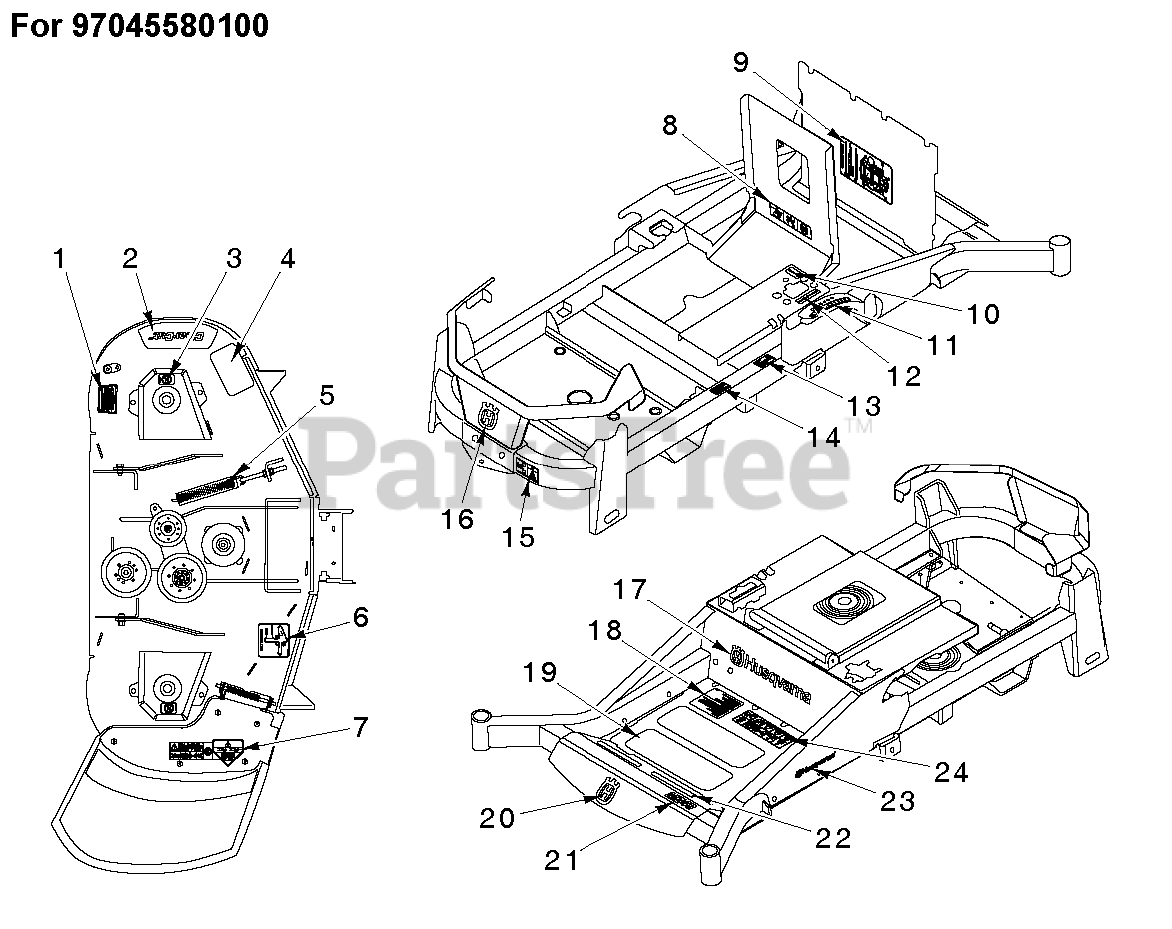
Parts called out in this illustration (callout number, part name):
1	DECAL DECK DECAL DECAL.DECK.WA
2	DECAL DECK DECAL DECAL.48DECK.
3	DECAL.DECK.CLEARCUT.NOSTEP
5	VIBRATION PAD
6	DECAL, BELT ROUTING
7	DECAL.TRACT/ZTR.DECKWARN.HUSQ
8	EURO DECAL-BATTERY WARNIN6
9	DECAL, SERVICE
10	DECAL.STR.S.T.SYSMBOLONLY.2014
11	DECAL, HEIGHT ADJUST
12	DECAL.ZTR.MOTCONTRL.SYMBOL.HUS
15	DECAL, BELT DRIVE
16	DECAL, CROWN H, 110MM
17	DECAL ZTR BRAND GRAPHIC DECAL.
18	DECAL.ZTR.STRTNGINST.REMOTECHK
19	ANTI-SKID PAD
20	DECAL.AUGER.HUSQ.CROWN.SNOW
21	DECAL ZTR MODEL NUMBER DECAL.Z
23	RP.DECAL.BADGE.170MM.TEXTLOGO
24	DECAL ZTR WARNING DECAL DECAL.
